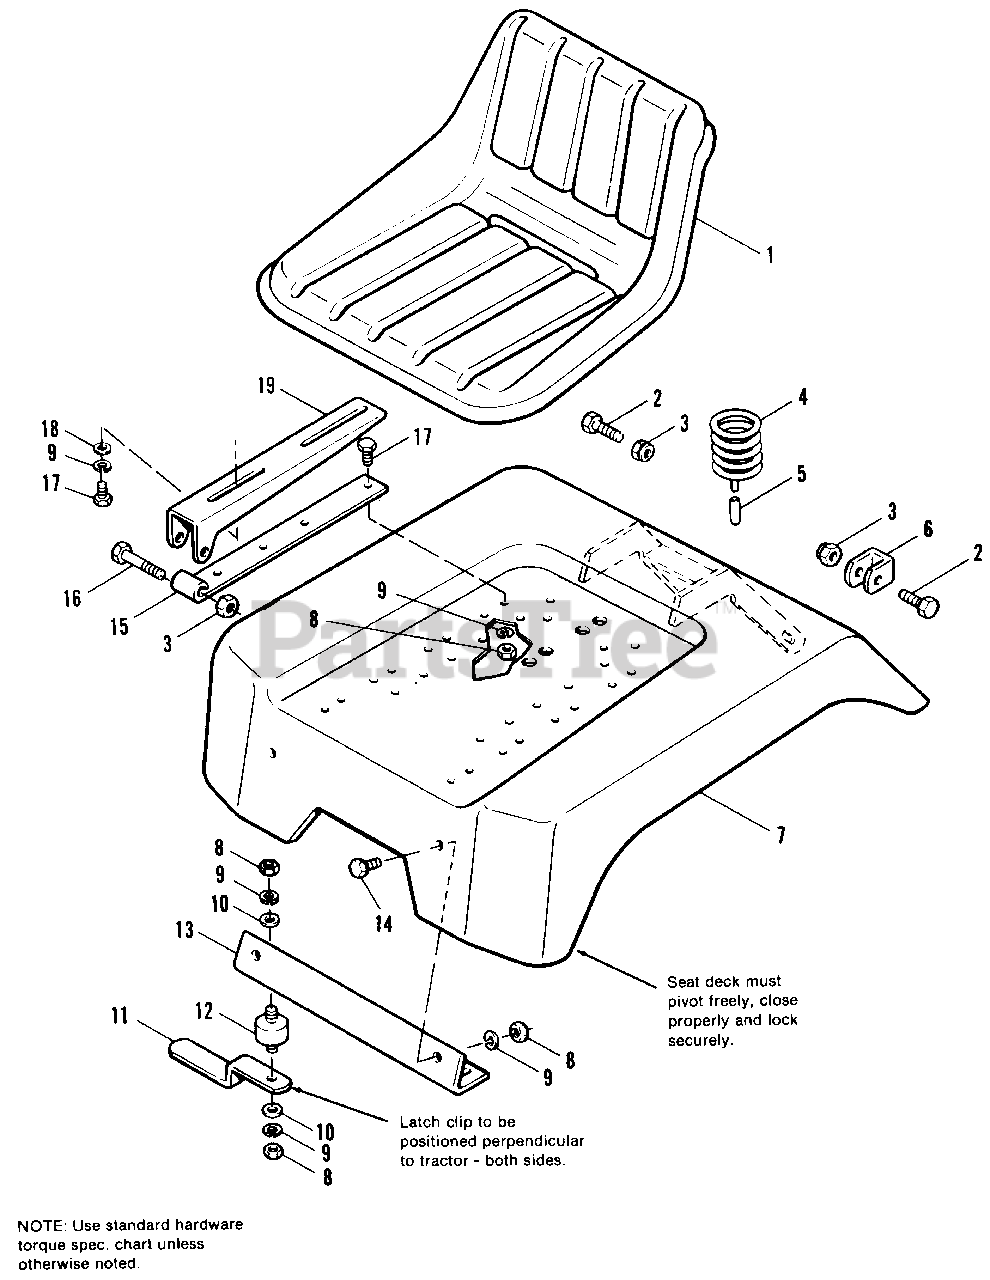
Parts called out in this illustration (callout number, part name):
2	CAPSCREW, Hex Hd., 3/8-16 x 1-1/4
3	LOCKNUT, Hex, 3/8-16
4	SPRING, Seat
5	COVER, Wire
6	STOP, Seat Deck
7	DECK ASSY., Seat
8	NUT, Hex, Full, 5/16-18
9	LOCKWASHER, 5/16
10	WASHER, Plain, 1/4
12	CONNECTOR, Cushion
13	BRACKET, Seat Deck, Front
14	CAPSCREW, Hex Hd., 5/16-18 x 5/8
15	HINGE, Lower
16	CAPSCREW, Hex Hd., 3/8-16 x 2
17	CAPSCREW, Hex Hd., 5/16-18 x 3/4
18	WASHER, Plain, 5/16
19	HINGE, Upper
